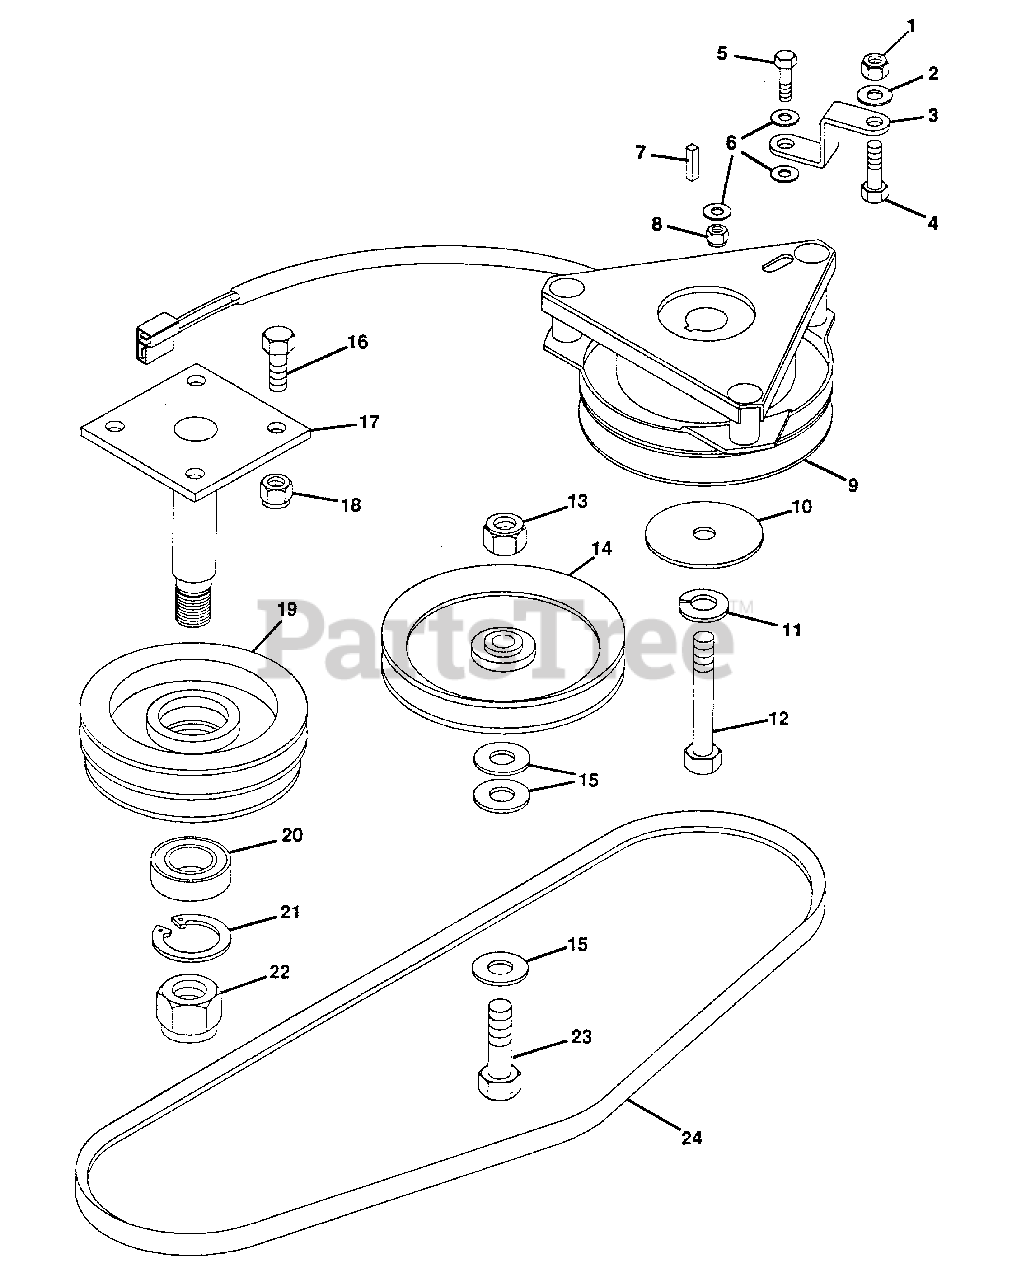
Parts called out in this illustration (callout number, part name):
1	NUT, LOCK 5/16-18
2	WASHER, FLAT .344X.688X.065
3	STOP, CLUTCH FRAME
4	BOLT, HEX 5/16-18X1.75
5	BOLT, HEX 1/4-20X.75
6	WASHER, FLAT .281X.625X.065
7	KEY, SQUARE .250X1.250
8	NUT, LOCK 1/4-20
9	CLUTCH, ELECTRIC
10	WASHER, SPECIAL
11	WASHER, LOCK 7/16 REG.
12	BOLT, HEX 7/16-20X3.00
13	NUT, LOCK 1/2-13
14	PULLEY, V-IDLER
15	WASHER, FLAT .531X1.250X.100
16	BOLT, HEX 3/8-16X1.00
17	WELDMENT, IDLER SUPPORT
18	NUT, LOCK 3/8-16
19	IDLER, TWO GROOVE
20	BEARING, BALL
21	RING, RETAINING
22	NUT, LOCK 3/4-16
23	BOLT, HEX 1/2-13X2.00
24	BELT
